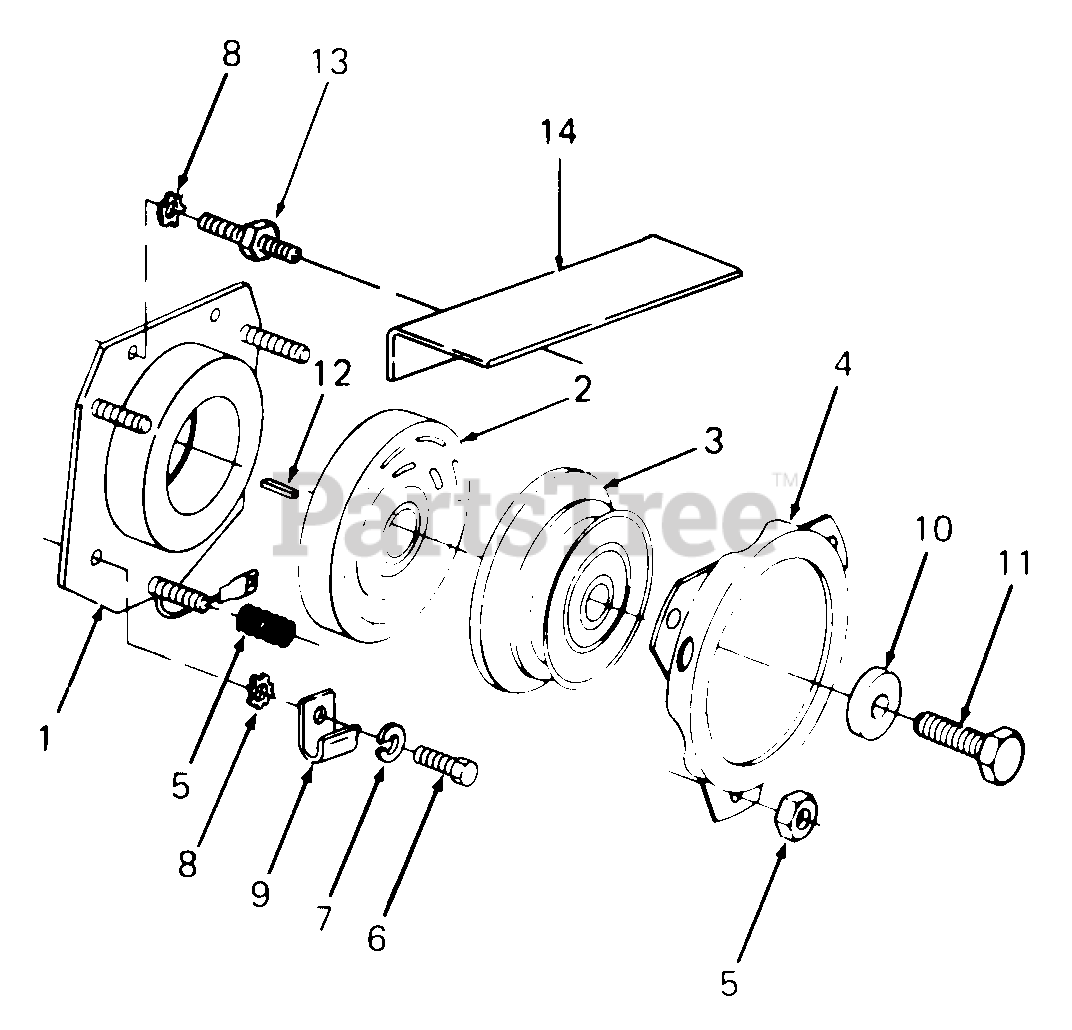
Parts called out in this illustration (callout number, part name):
4	Drum, Brake
5	Spring & Nut Kit
6	Screw, Hex Cap, 7/16-14 x .75 Lg GR5
7	Washer, Lock, 7/16
8	Washer, Ext. Lock, .45 x .75 x .035 Thk
9	Clamp, Cable
10	Washer, Flat, .47 x 1.5 x .225 Thk
11	Screw, Hex Cap, 7/16-20 x 1.25 Lg GR5
12	Key, Square, 1/4 x .75 Lg
13	Stud, 7/16-14 Trd
14	Baffle, PTO
